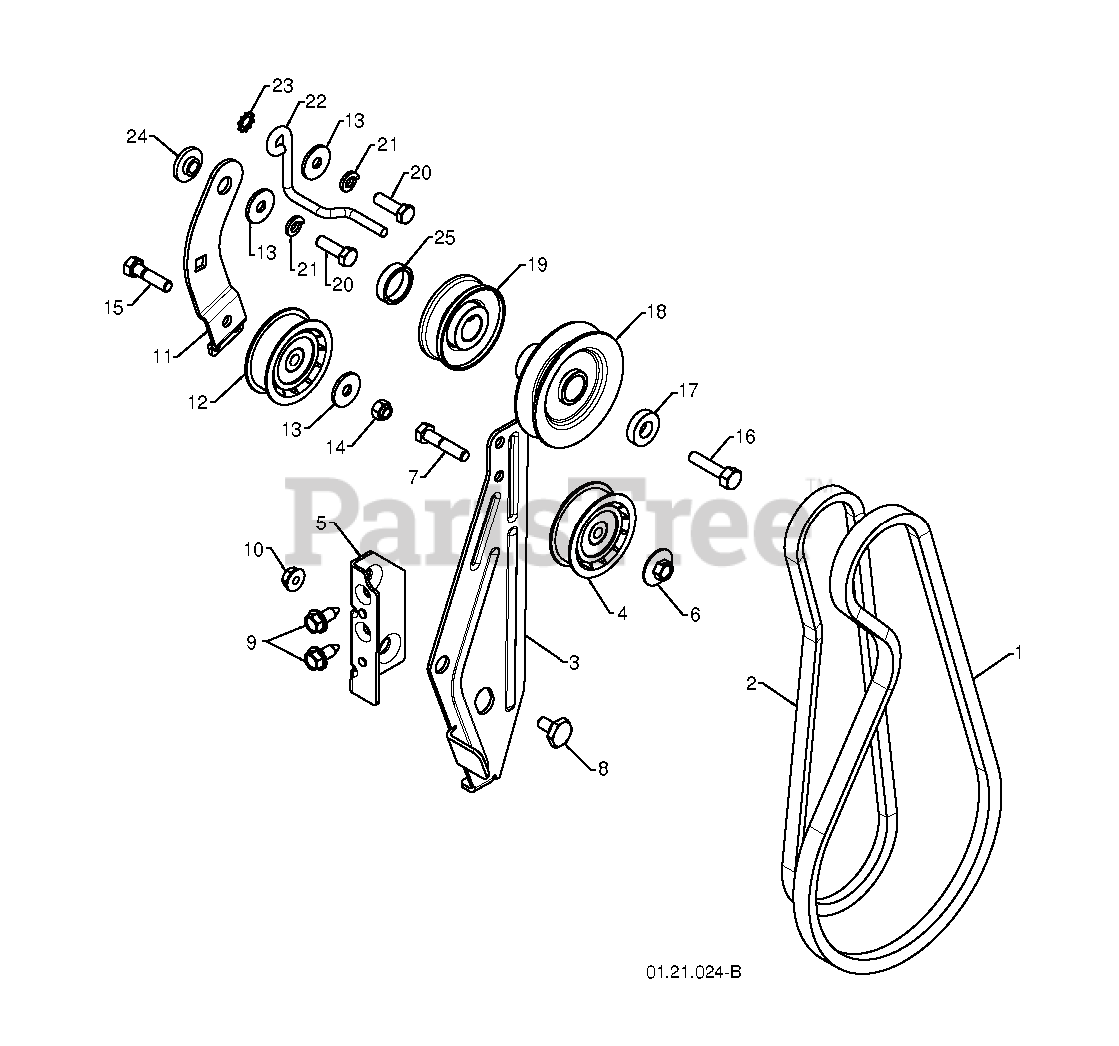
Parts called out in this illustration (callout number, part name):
1	VBELT; IMPELLER_39.09
2	TRACTION BELT
3	ARM.IDLER.BRAKE
4	PULLEY.IDLER.W/SPACER.
5	RP BRACKET.IDLER
6	NUT.FLANGE.HEX.5/16X18.BLACK
7	HEX BOLT
8	BOLT.SHOULDER.1/2X12
9	NUT.LOCK.5/16-18
10	BOLT.HEX.HD.WASHER.5/16-18X.75
11	ARM, IDLER
12	PULLEY.W/SPACER.2.25
13	STEEL WASHER
14	NUT.71038.31-18.HEX.NYLOCK
15	BOLT.5/16-18X1-1/4 FULL.THREAD
16	SCREW, HEX HD 3/8-24 X 1-3/8
17	WASHER, FLAT 3/8
18	PULLEY.ENG.IMPELLER.SNOW
19	PULLEY,ENGINE TRACTION DRIVE
21	WASHER.LOCK.HVY.HLCL.SPR.5/16
22	GUIDE.BELT.HYDRO.H
23	WASHER EXT TOOTH LOCK 5/16
24	RP BUSHING, IDLER PIVOT
25	SPACER.ENGINE.PULLEY
